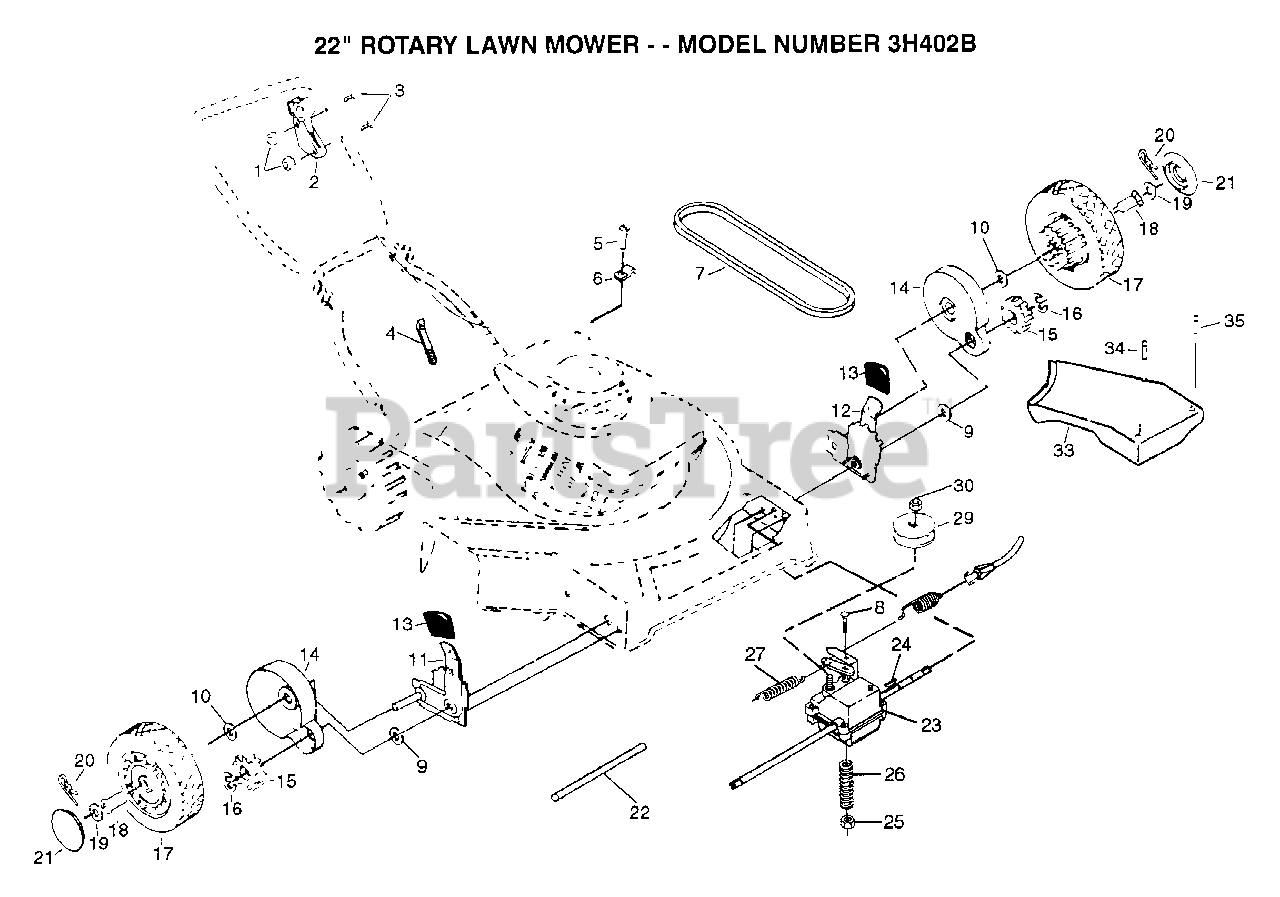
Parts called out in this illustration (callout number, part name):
1	LOCKNUT
2	CONTROL.DRIVE
3	SCREW
5	TAPPING SCREW
6	GUIDE CLIP PM
8	BOLT.1/4-20X2.0
9	WASHER PM
10	WASHER FLUT
13	KNOB PM
14	DUST SHROUD PM
15	PINION.GEAR
16	E-RING.7/16.RE.
17	WHEEL.8X2.LP.PR
18	BUSHING.ROUND
19	WASHER
20	RETAINER CLIP PM
21	HUB CAP
22	DRV SHAFT TUBE PM
24	HI PRO KEY
26	SPRING.TENSION
27	SPRING
29	PULLEY.DRIVEN
30	LOCKNUT
33	COVER DRIVE BLK
